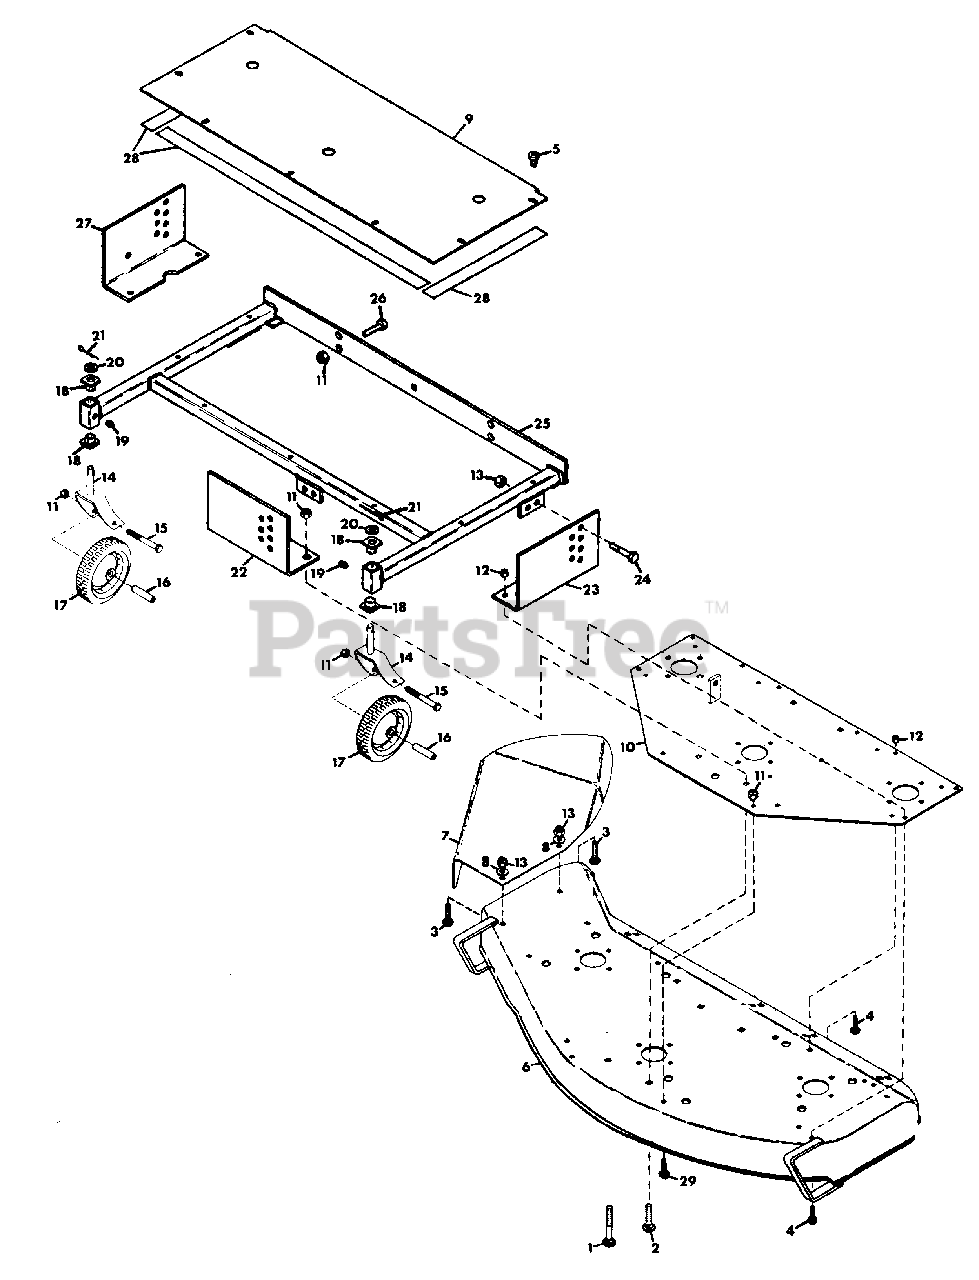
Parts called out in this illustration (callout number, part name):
1	BOLT, 1/2-13X3.50 RD HD SQ NK
2	BOLT, 1/2-13X1.00 RD HD SQ NK
3	BOLT, CARRIAGE 3/8-16X.75
4	BOLT, CARRIAGE 5/16-18X1.00
5	SCREW, 1/4-20X.50
6	WELDMENT, 50" DECK
7	SHIELD, SAFETY EXT. 50" MOWER
8	WASHER, FLAT .406X.812X.065
9	GUARD, 50" MOWER BELT
10	WELDMENT, SUPPORT PLATE
11	NUT, LOCK 1/2-13
12	NUT, LOCK 5/16-18
13	NUT, LOCK 3/8-16
14	WELDMENT, CASTER FORK
15	BOLT, HEX 1/2-13X5
16	BUSHING, WHEEL
17	WHEEL, GAUGE
18	BEARING, FLANGED
19	FITTING, LUBE 1/4-28
20	WASHER, FLAT .812X1.375X.100
21	PIN, COTTER .187X1.50
22	BRACKET, FRONT SUPPORT
23	BRACKET, SIDE SUPPORT L.H.
24	BOLT, HEX 3/8-16X1.00
25	WELDMENT, FRAME SUPPORT
26	BOLT, HEX 1/2-13X1.50
27	BRACKET, SIDE SUPPORT R.H.
28	TAPE, VINYL FOAM(75' ROLL)
29	BOLT, HEX 1/2-13X1.25
NS	DECAL, GRAVELY LOGO
NS	DECAL, DANGER HAND
NS	DECAL, DANGER FOOT
NS	DECAL, WARNING EYE
